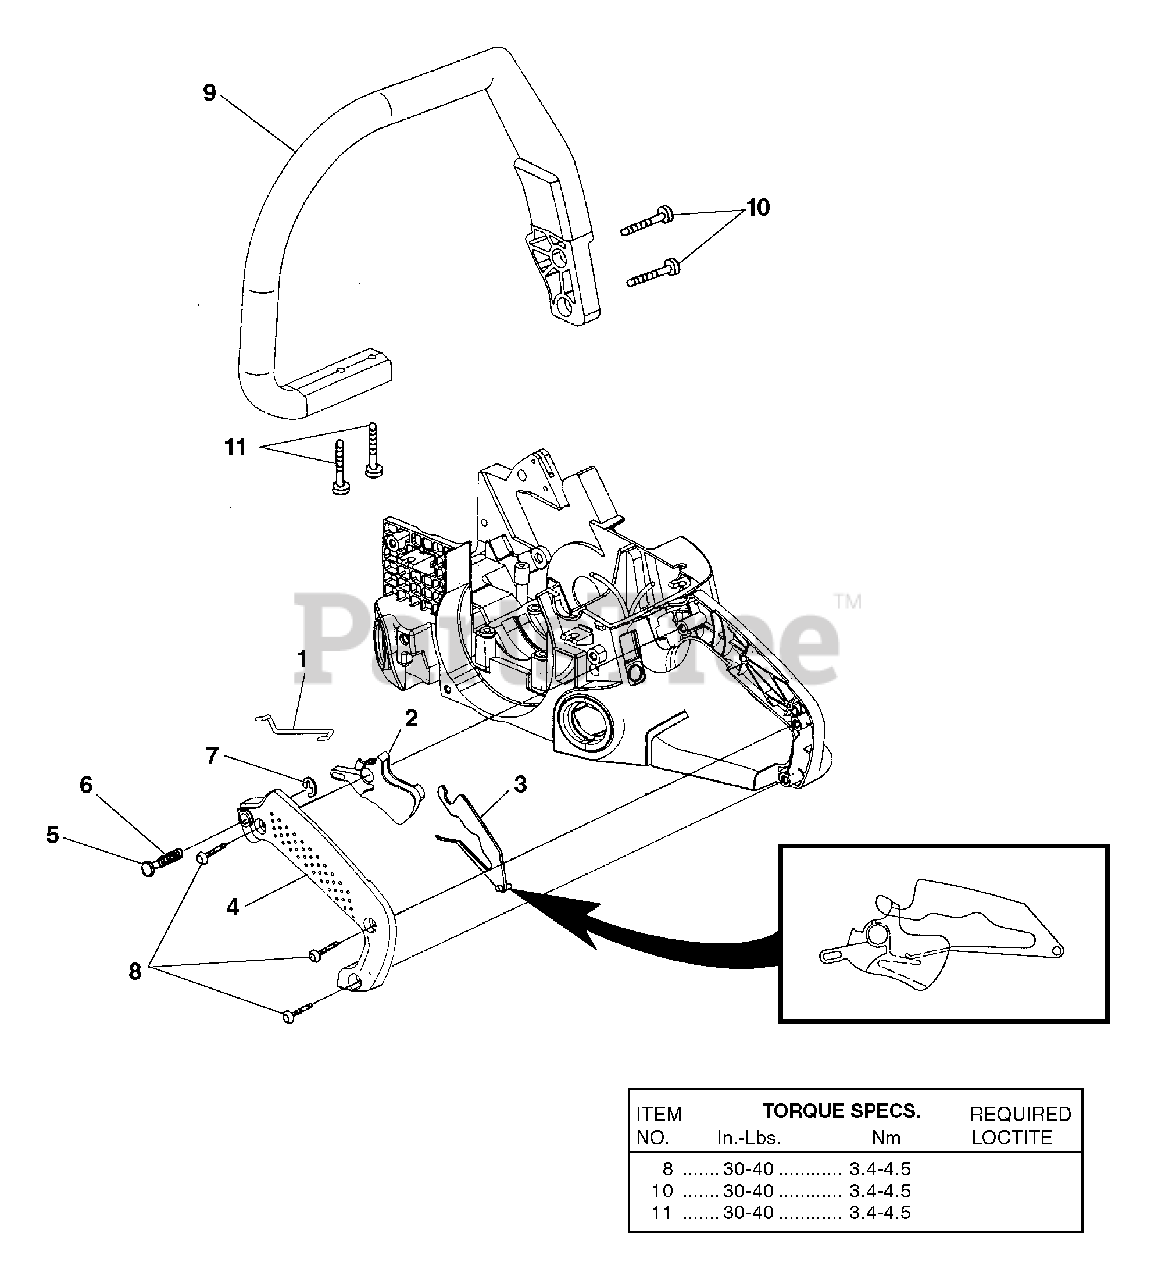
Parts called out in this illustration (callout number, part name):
1	Throttle Wire
2	Trigger, Throttle
3	Throttle Lock Out
4	Handle Cover Kit
5	Throttle Lock Pin
6	Spring, Compression
7	Ring, Retainer
8	Screw, Thread Form., Plastite (10-14 x 3/4")
9	Front Handle Kit
10	Screw, Plastite (10-14 x 5/8")
11	Screw, Truss Hd.
